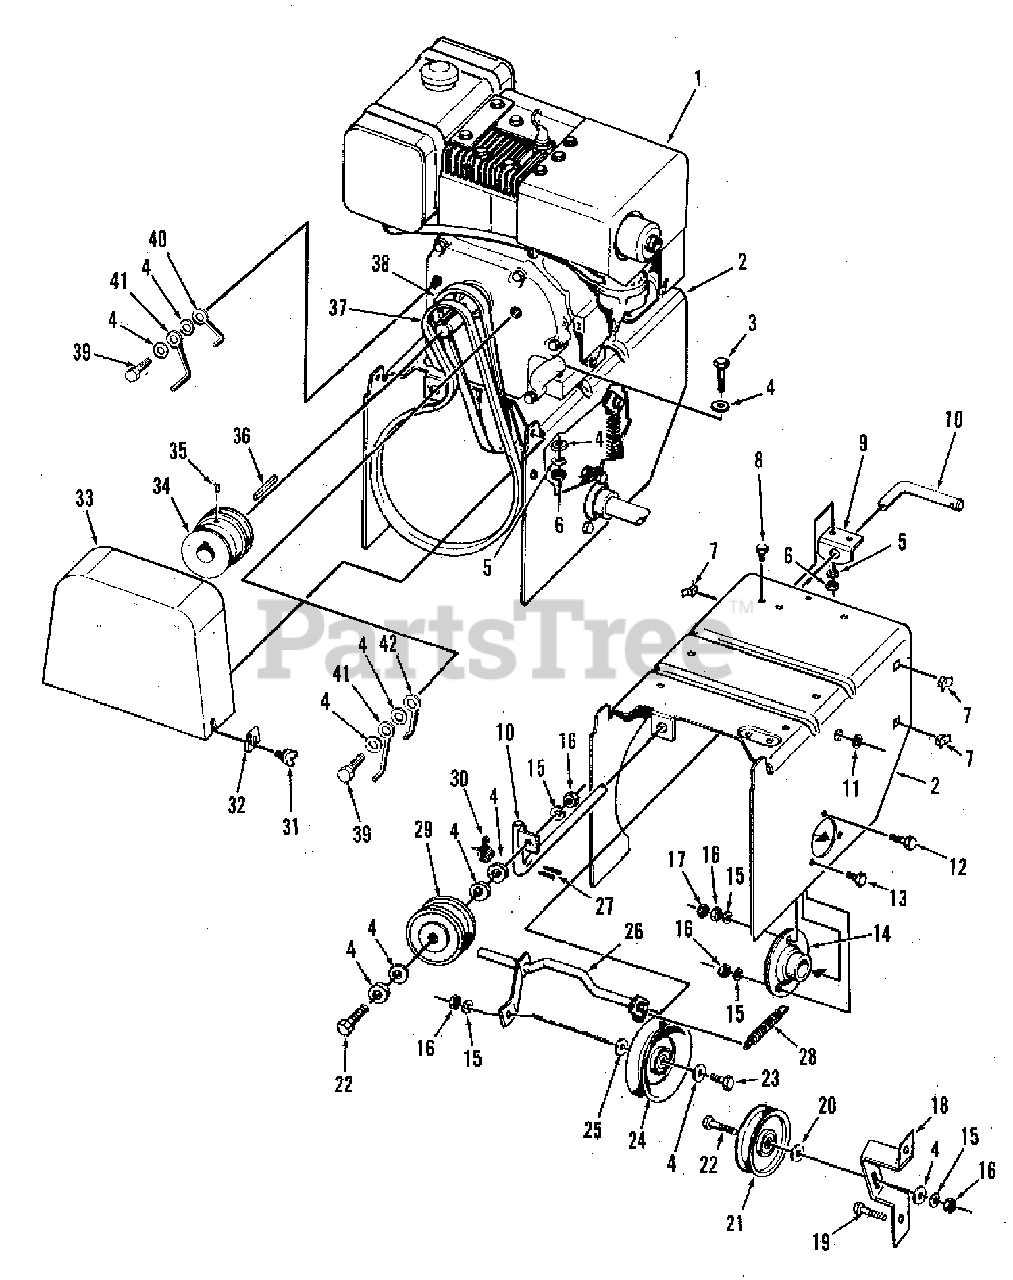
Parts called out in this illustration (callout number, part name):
2	ENGINE BASE & FRAME
3	SCREW, Hex Cap, 5/16-18 x 1-3/4"
4	WASHER, Flat, 5/16
5	WASHER, Lock, 5/16"
6	NUT, 5/16-18
7	NUT, Tinnerman
8	SCREW, Hex, 5/16-18 x 5/8
9	BRACKET, Idler Support
10	ROD ASSEMBLY, Auger
11	RING, Retaining
12	SCREW, Hex Cap, 3/8-16 x 1-1/4
13	SCREW, Hex Cap, 3/8-16 x 1
14	BEARING, Ball
15	WASHER, Lock, 3/8
16	NUT, Hex, 3/8-16
18	BRACKET, Idler
19	SCREW, 3/8-16 x 1/2, Taptite
21	PULLEY, Idler
22	SCREW, 3/8-16 x 1-1/2
23	SCREW, 3/8-16 x 2
24	PULLEY, Idler
26	CLUTCH PULLEY PIVOT
27	PIN, Cotter, 5/32 x 1
28	SPRING, Tension
29	PULLEY, Idler
30	SPRING, Torsion
31	SCRWE, Thumb, 5/16-18 x 3/4
32	NUT, Tinnerman
33	COVER, Engine Pulley
34	PULLEY, Engine
35	SCREW, Set, 5/16-18 x 3/8
39	SCREW, Hex, 5/16-24 x 1
